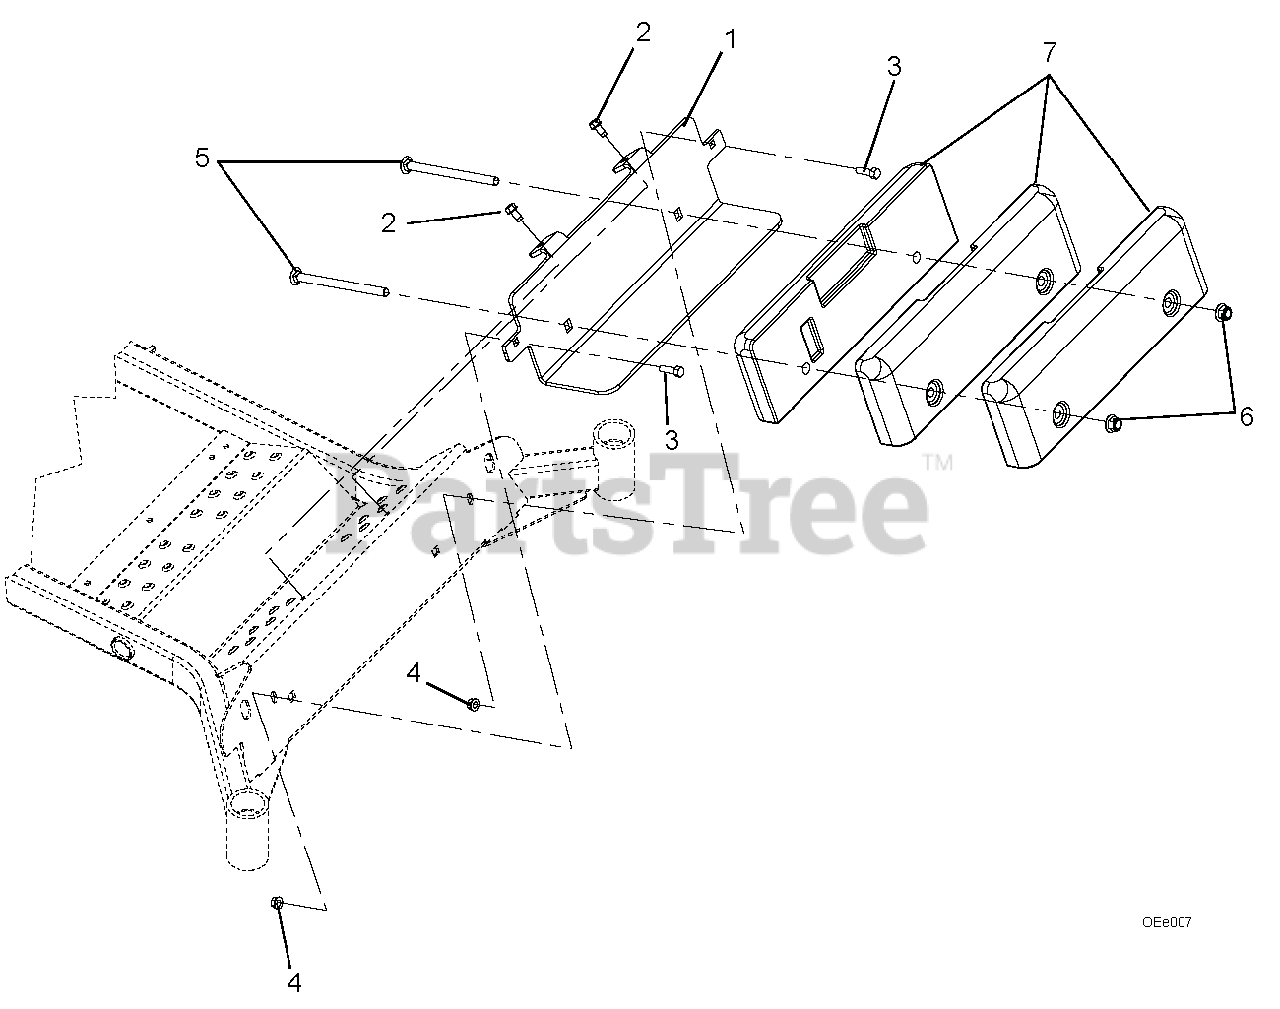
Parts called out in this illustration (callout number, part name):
1	CZ-HD COUNTERWEIGHT BRKT - BLK
2	@SCR-TAP .38-16X.75 HWH TR YWZ
3	@BLT-RDHDSQNK .38-16X1.25 G5YZ
4	@NUT-LK-TOP-FLG .38-16 YWZC
5	@BLT-RDHDSQNK .50-13X7.00 G5YZ
6	@NUT-LK-NYL-FLG .50-13 YWZC
7	WEIGHT, CAST IRON
